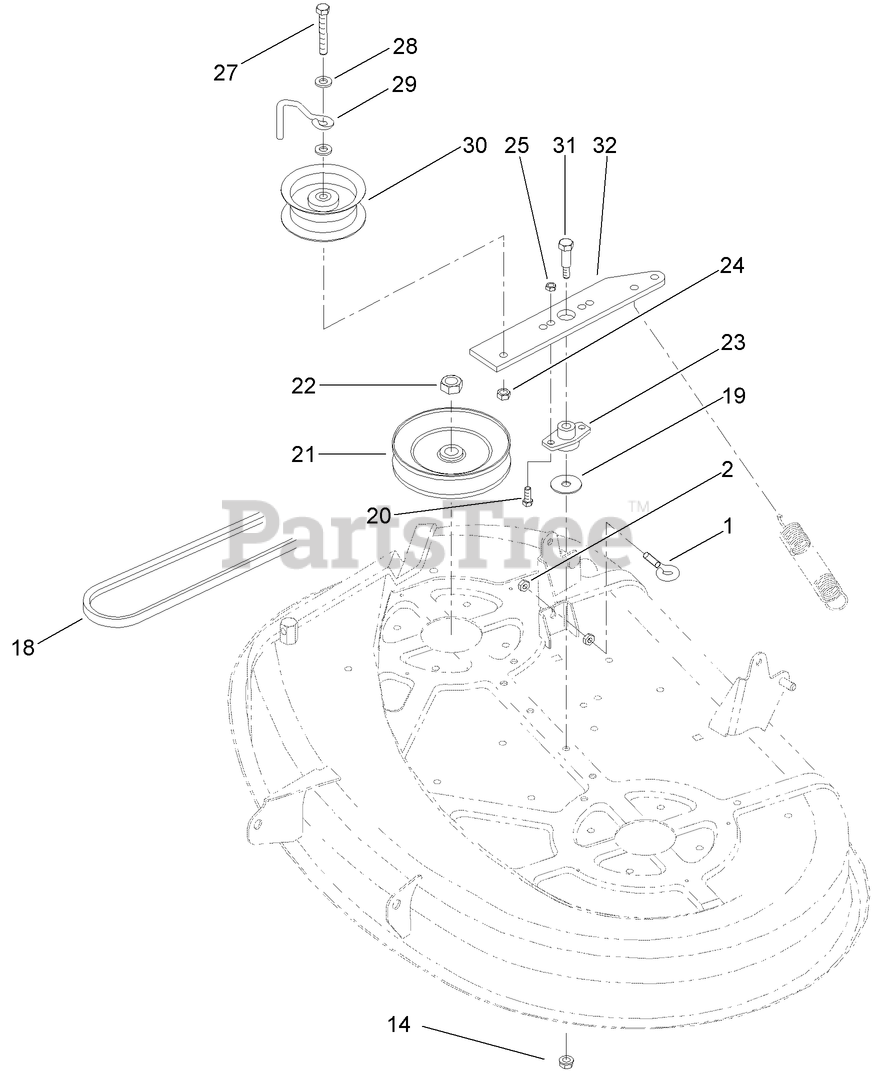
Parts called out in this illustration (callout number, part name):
1	EYEBOLT
2	NUT-JAM
14	NUT-LOCK, NI
18	V-BELT
19	WASHER-FLAT
20	SCREW-HH
21	PULLEY
22	NUT-HEX
23	BUSHING-ARM, IDLER
24	NUT-LOCK, NI
25	NUT-LOCK, NI
27	SCREW-HH
28	WASHER-FLAT
29	GUIDE-IDLER, BELT
31	SCREW-SHOULDER, HH
32	ARM-IDLER
